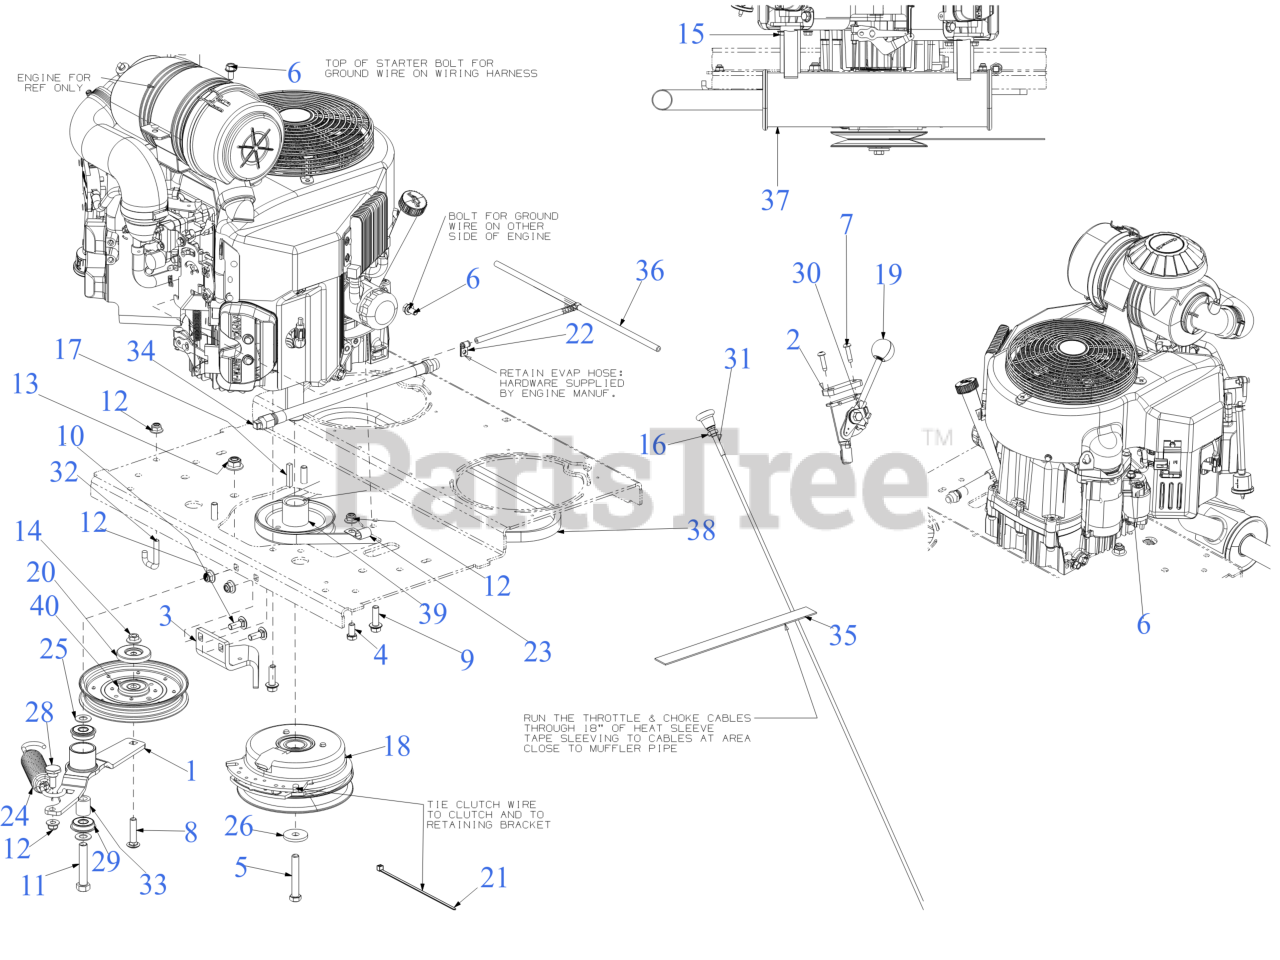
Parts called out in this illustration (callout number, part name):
1	TRANSMISSION IDLER BRACKET
3	CLUTCH RETAINER BRACKET
4	HEX SCREW 3/8-16 x .75
5	SCREW 7/16-20:2.75 GR5
6	SCREW M8 x 1.25 x 16MM GR8.8
7	SCREW 1/4-20 x 1.0
8	CARRIAGE BOLT 3/8-16 x 1.75 GR5
9	SCREW 3/8-16 x 1.25 GR5
10	CARRIAGE BOLT 3/8-16 x 1.00 GR5
11	SCREW 1/2-13 x 2.75 GR5
14	FLANGE LOCK NUT
15	HEX FLANGE NUT
16	HEX JAM NUT 3/8X24
17	SQUARE KEY 1/4 x 1.50
18	ELECTRIC PTO CLUTCH
20	PULLEY CAP
21	7" CABLE TIE
22	MOUNTING CLAMP
23	J TYPE CLIP
24	EXTENSION SPRING W/HOOK
25	FLAT WASHER .510 x .995
26	FLAT WASHER .45 x 1.5 x .172 HT
28	SHOULDER SCREW .625 x .302 x 3/8-16
29	ROLLER BEARING .5X1.37X.44
30	THROTTLE CABLE 59"
31	CHOKE CABLE
32	ROD SPRING HOOK
33	SPACER 0.51 x 0.88 x 1.00
34	OIL DRAIN HOSE
35	HEAT SHIELD 24"
36	ROLLOVER VENT HOSE ASSEMBLY
37	MUFFLER - KAWASAKI 1000
38	TRANSMISSION BELT
39	PULLEY - PUMP DRIVE
40	IDLER PULLEY
